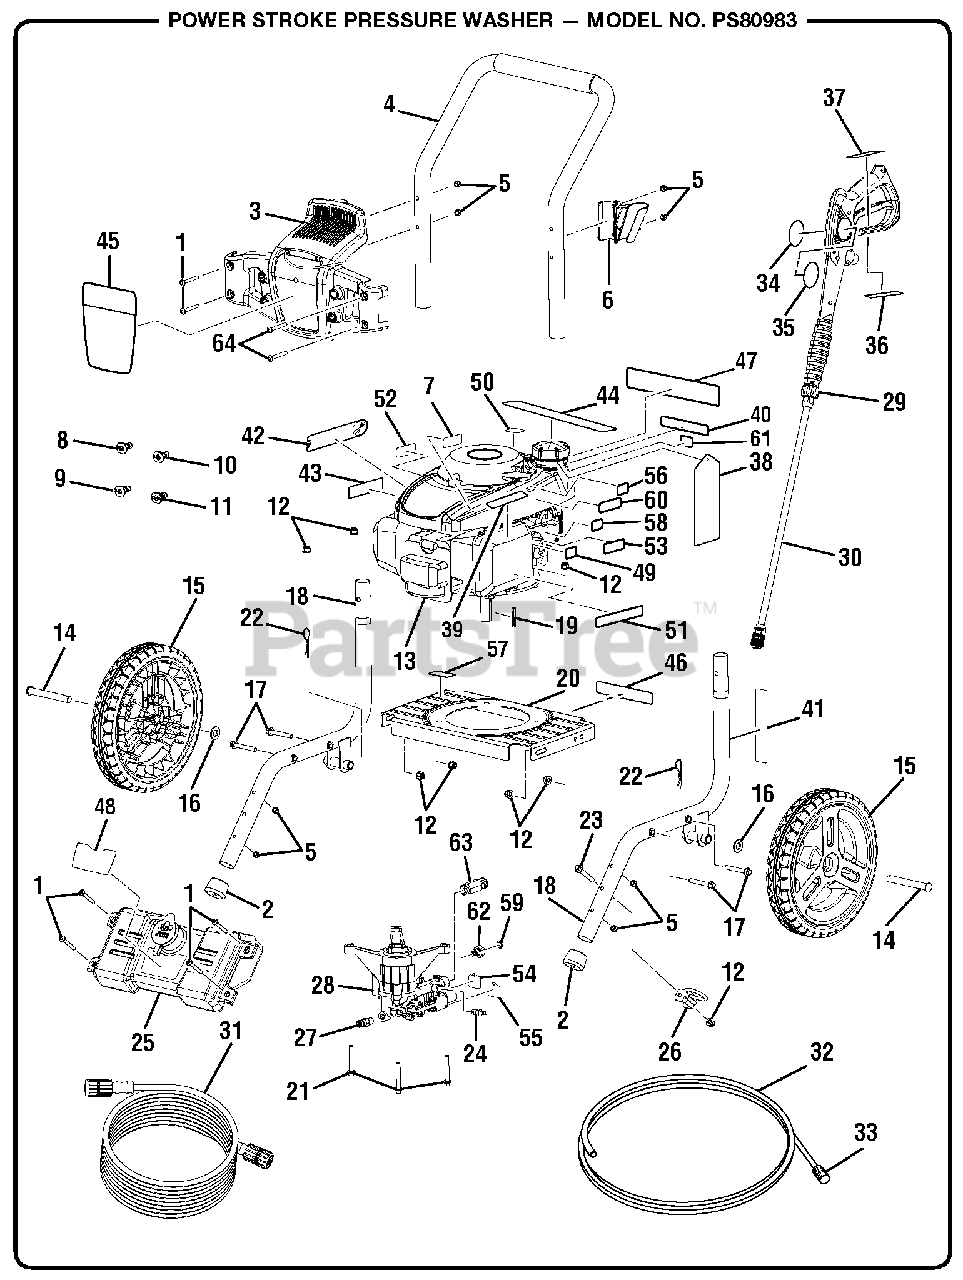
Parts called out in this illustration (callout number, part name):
1	Screw (1/4-20 x 1.85 in., T30 Torx Hd.)
2	Rubber Foot
3	Hose and Nozzle Holder Assembly
4	Handle w/Foam
5	Lock Nut (1/4-20)
6	Wand Holder
7	EMC Label
8	40deg Nozzle
9	Soap Nozzle
10	25deg Nozzle
11	0deg Nozzle
12	Flange Nut (M8 x 1.25)
16	Washer (1/2 in.)
17	Bolt (M8 x 55 mm, Flange Hd.)
18	Main Frame Assembly
19	Output Shaft Key (40 mm)
20	Engine Plate
21	Bolt (M8 x 60 mm, Flange Hd.)
22	Axle Clip
23	Bolt (M8 x 50 mm)
24	Detergent Suction Kit
25	Soap Tank w/Cap
26	Wand Holder Loop
27	Thermal Release Valve
28	Pump
29	Trigger Handle Assembly
30	Extension Wand
31	Hose (25 ft., 3100 psi)
32	Chemical Siphon Tube
33	Chemical Siphon Filter
34	Label (Wand Logo)
35	Label (Wand Warning)
36	Fr/Sp Label (Wand Warning)
37	Label (Wand Rating)
38	Danger Hangtag
39	Inquiries Label
40	Combustion Label
41	Pump Quick Start Label
42	Add Oil Hangtag
43	Hot Surface Label
44	No Oil Label
45	Performance Label
46	Data Label
47	Danger Label
48	Soap Tank Label
49	Engine On/Off Label
50	No E85 Label
51	Engine Quick Start Label
52	Lubricant Label
53	Choke/Run Label
54	Garden Hose Hang Tag
55	High Pressure Hose Hang Tag
56	Recoil Start Label
57	Oil Fill Location Label
58	Choke Label
59	Filter Screen (Pump Inlet)
60	Release Water Label
61	Costco Tech Support Label
62	Inlet Tube
63	Outlet Tube
64	Screw (1/4-20 x 2 in., T30 Torx Hd.)
